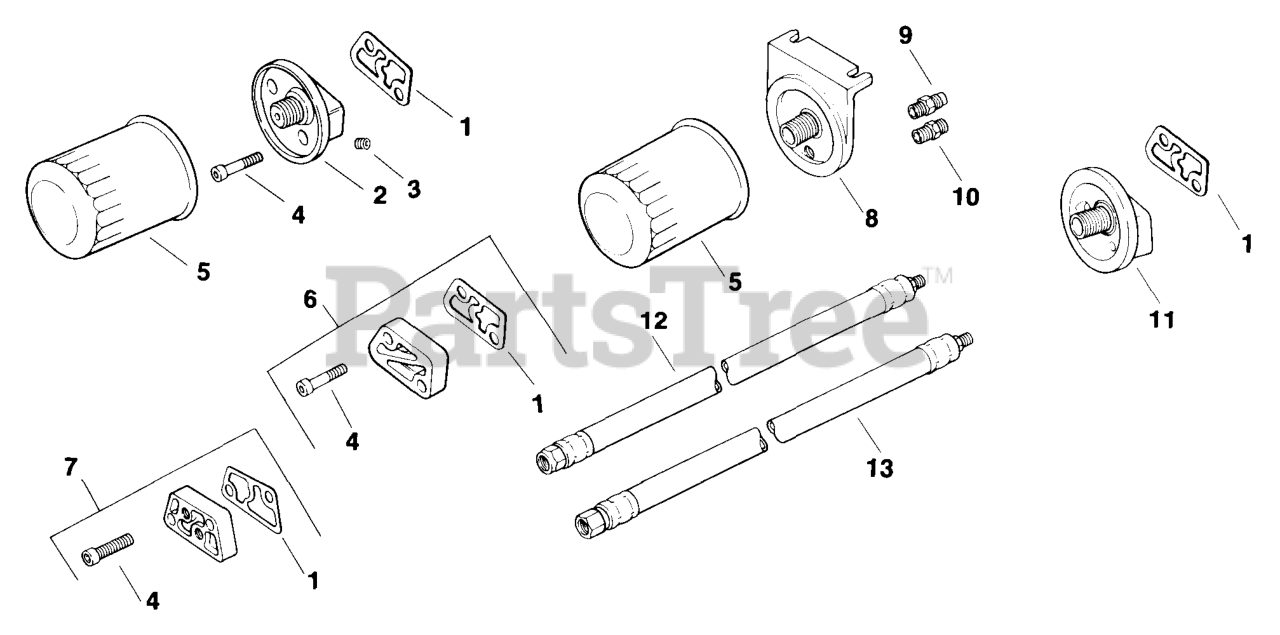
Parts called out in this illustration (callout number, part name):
1	Gasket, Oil Filter
4	Screw, Hex. Socket Hd. Cap 5/16-18x1-1/4"
5	Oil Filter
11	Adapter, Oil Filter
